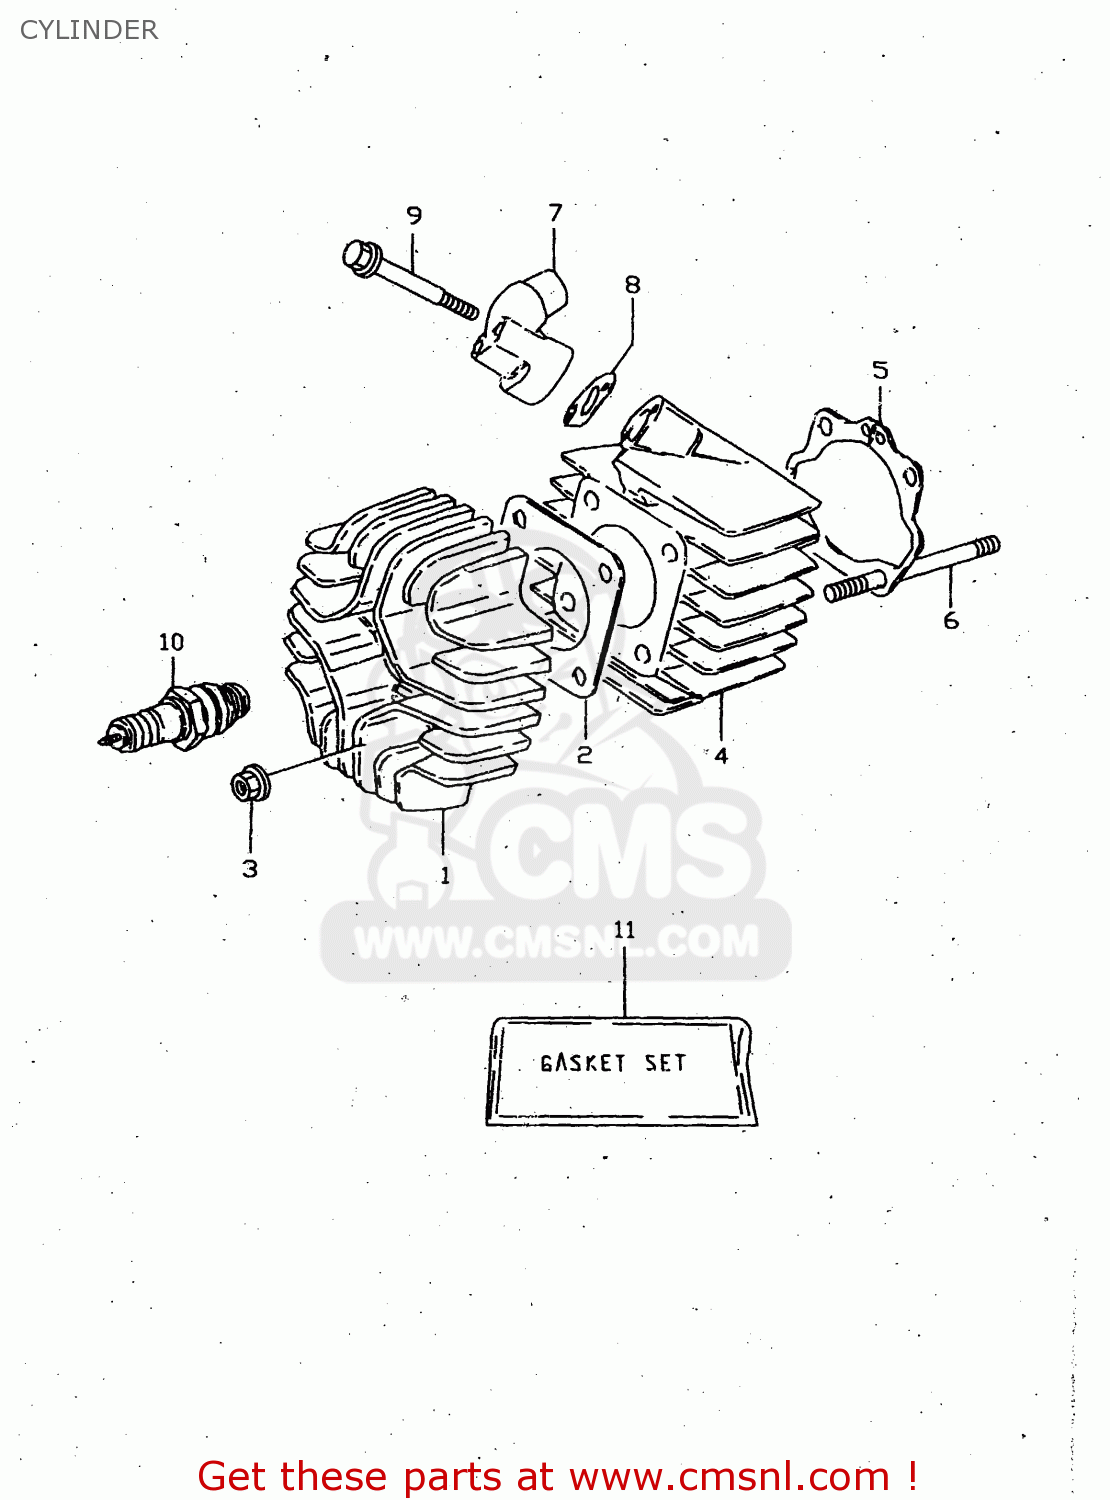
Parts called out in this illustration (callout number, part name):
1	HEAD,CYLINDER
2	GASKET,CYLINDER HEAD (NAS)
3	NUT
4	CYLINDER
5	GASKET,CYLINDER (NAS)
6	BOLT,STUD
7	PIPE,INTAKE
8	GASKET,INTAKE PIPE (NAS)
9	BOLT
10	SPARK PLUG W14FPR-UL
11	GASKET SET (NAS)
